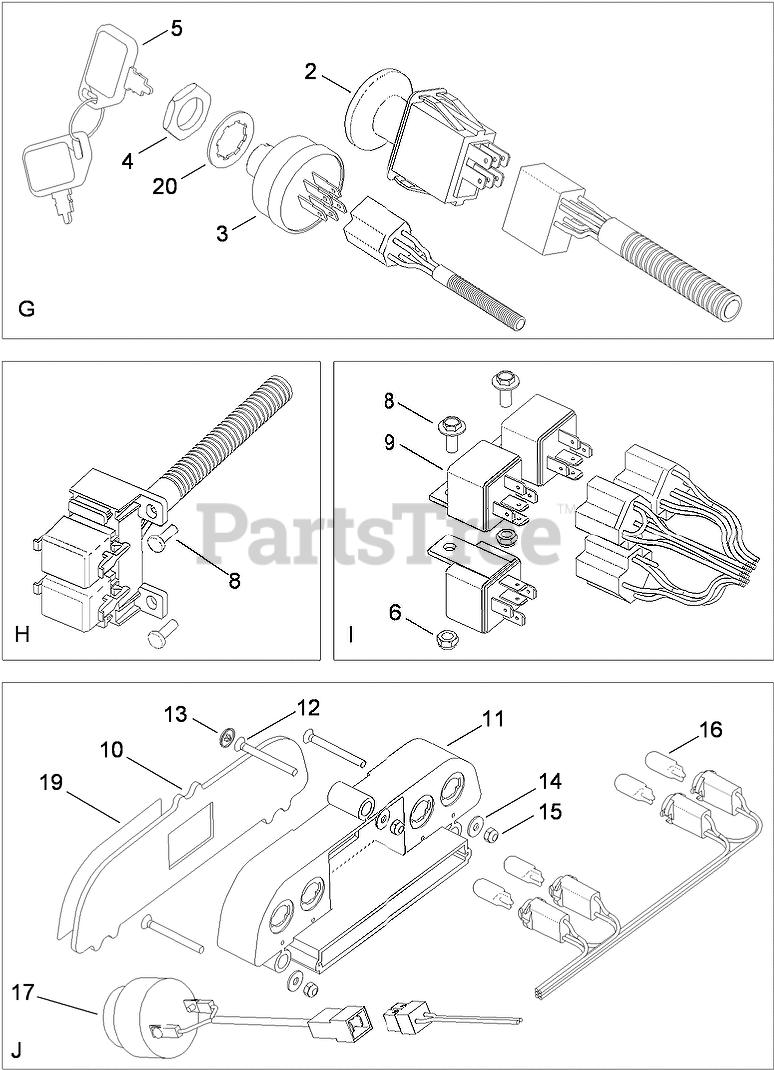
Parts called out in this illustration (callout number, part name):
2	SWITCH-PTO
3	SWITCH-IGNITION
4	NUT-HH
5	KEY-IGNITION
6	NUT-LOCK
8	SCREW-HEX
10	LENS-DASH LIGHTS
11	HOUSING-LIGHT, INDICATOR
13	CAP-SCREW
14	WASHER
15	NUT-HEX
17	BUZZER
19	DECAL-DASH
20	WASHER-TOOTH, INTERNAL
